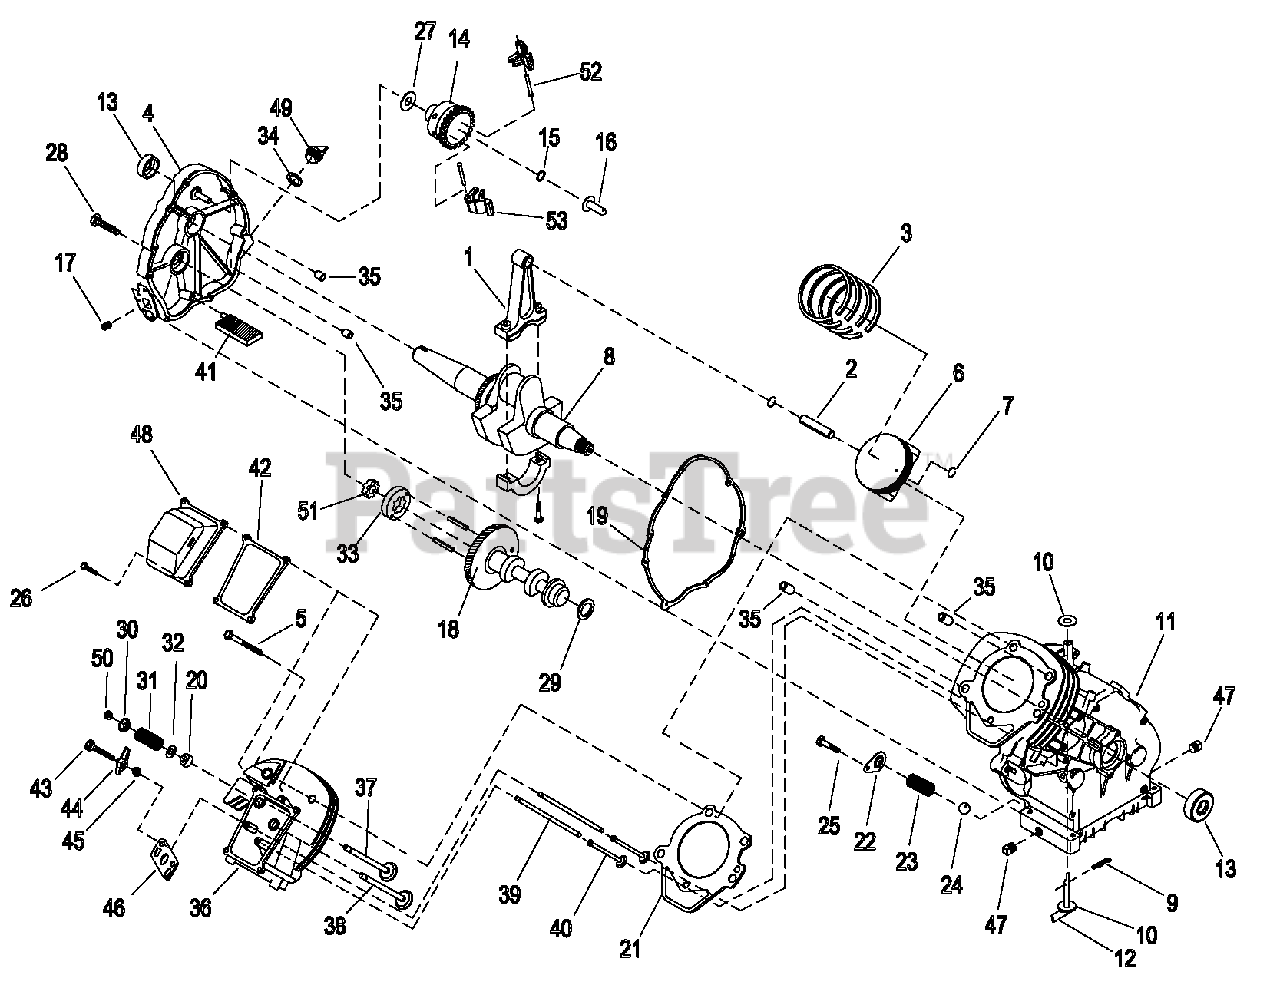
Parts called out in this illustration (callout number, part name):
1	ASSY, CONNECTING ROD
2	PIN, PISTON
3	RING SET, 75 DIAMETER
4	ASSY, GEAR COVER
5	SCREW, HHC M8-1.25 X 56
6	PISTON, COATED 75 DIAMETER
7	RETAINER, PISTON PIN
8	ASSEMBLY, CRANKSHAFT
9	PIN, "R"GOVERNOR ARM
10	WASHER, FLAT 1/4", 0.15 THICK
11	CRANKCASE GH220 HS
12	ARM, GOVERNOR
13	SEAL, 28mm DIA x 41.47 VITON
14	ASSY, GOVERNOR GEAR
15	C-RING, GOVERNOR GEAR RETAINING
16	SPOOL, GOVERNOR MACHINED
17	PLUG, 1/8" NPTF PIPE
18	ASSY, CAMSHAFT 220 W/ COMP. RELEASE
19	GASKET, CRANKCASE
20	SEAL, VALVE STEM
21	GASKET, CYLINDER HEAD GH220
22	COVER, OIL PRESSURE RELIEF
23	SPRING, OIL PRESSURE RELIEF GH220
24	BALL, 11/32" DIAMETER PRESSURE RELIEF
25	SCREW, HHTT M5-0.8 X 10
26	SCREW, M6-1.0 x 12 W/LOCK WASHER
27	WASHER, THRUST GOVERNOR GEAR
28	SCREW, HHFC M8-1.25 x 35
29	WASHER, SPRING
30	RETAINER, VALVE
31	SPRING, VALVE
32	WASHER, VALVE SPRING WEAR
33	GEROTOR, OUTER
34	O-RING, 11/16-7-8" 75 DUROMETER VITON
35	SLEEVE, DOWEL PIN 12mm DIAMETER
36	ASSEMBLY, HEAD GUIDES & SEATS 220
37	VALVE, EXHAUST
38	VALVE, INTAKE
39	PUSHROD, 145.76 LENGTH GH220
40	TAPPET, 7.5mm DIAMETER
41	ASSEMBLY, OIL PICK UP GH220
42	GASKET, VALVE COVER
43	STUD, ROCKER ARM PIVOT
44	ARM, ROCKER GH220
45	NUT, JAM M-6 – 0.75 FINE THD
46	PLATE, PUSHROD GUIDE
47	PLUG, 1/4" NPTF PIPE
48	ASSEMBLY, VALVE COVER STEEL
49	PLUG, OIL FILL PLASTIC
50	KEEPER, VALVE SPRING
51	GEROTOR, INNER
52	PIN, GOVERNOR FLYWEIGHT RETAINER
53	FLYWEIGHT, GOVERNOR
